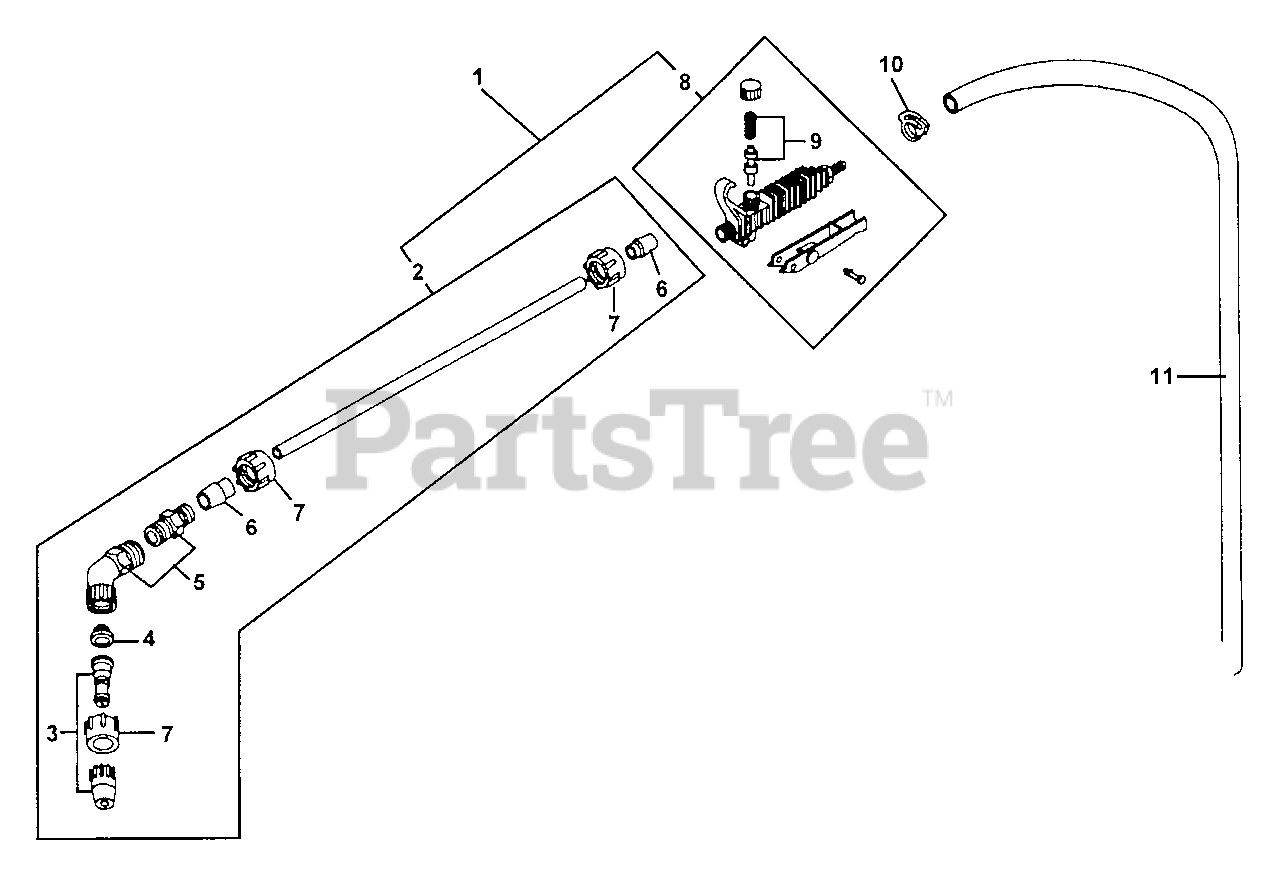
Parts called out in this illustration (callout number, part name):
1	SPRAY GUN ASSY
2	WAND ASSY
3	ADJUSTABLE SPRAY TIP ASSY
4	FILTER
5	FITTING - 45"
6	SEAL, FERREL
8	SPRAY TRIGGER ASSY
9	VALVE KIT TRIGGER ASSY
10	CLAMP, HOSE
11	HOSE - 3/8 I.D. X 48"
